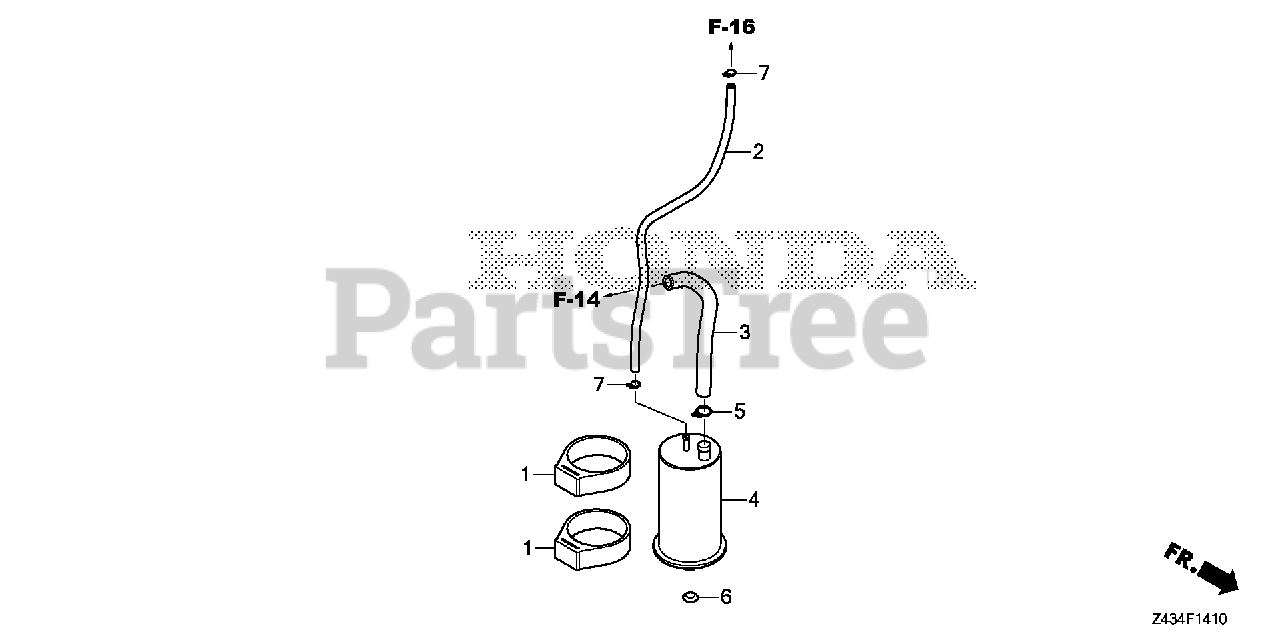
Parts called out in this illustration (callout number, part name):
1	RUBBER, CANISTER MOUNTING
2	TUBE, CANISTER CHARGE
3	TUBE, CANISTER PURGE
4	CANISTER ASSY.
5	CLIP, TUBE
6	PLUG, HOLE (8MM)
7	CLIP, TUBE (B8)
